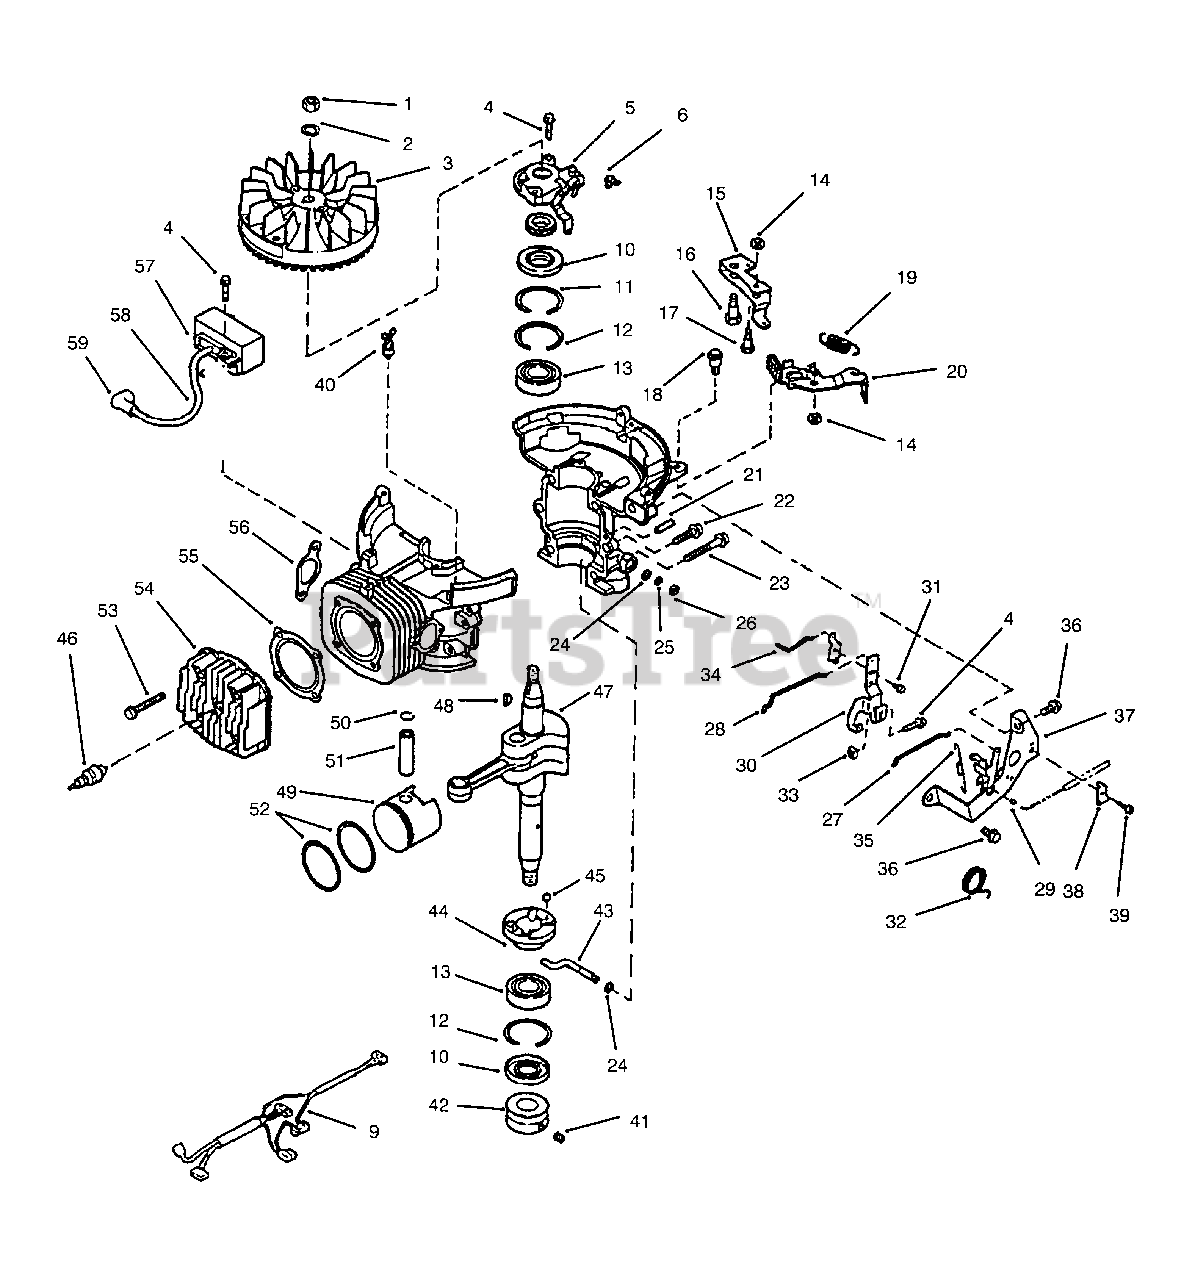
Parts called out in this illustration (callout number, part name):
1	Nut-Flywheel
2	Lockwasher
3	Flywheel (Model No.10590)
3	Flywheel (Model No.10591)
5	Oil Pump Kit w/Oil Lines (Incl. Ref. No. 6)
6	Clamp-Oil Line
9	Wire Harness (10591)
9	Wire Harness (10590)
10	Oil Seal-Crankshaft
11	Ring-Retaining
12	Ring-Retaining
13	Bearing-Crankshaft
14	Nut (Model No.10590)
15	Brake Actuator (Model No.10590)
16	Shoulder Bolt
17	Shoulder Bolt (Model No.10590)
18	Shoulder Bolt (Model No.10590)
19	Brake Spring (Model No.10590)
20	Brake & Switch (Model No.10590)
21	Pin-Taper
24	Washer-Governor Shaft
25	Ring-Retain.-Gov. Shaft
26	Seal-Oil, Governor Shaft
27	Rod-Choke
28	Rod-Throttle
29	Retainer-Throttle Wire
30	Kit-Gov. & Oil Pump Lever (Incl. Ref. No. 31)
32	Spring-Torsion
34	Rod-Oil Pump Control
35	Spring-Governor
37	Assy.-Governor Bracket (Model No.10590) (Incl. Ref. No. 32)
37	Assy.-Bracket & Switch (Model No.10591) (Incl. Ref. No. 32)
38	Clamp-Throttle Cable
40	Wire Tie (Model No.10591)
41	Screw-Set, Engine Pulley
42	Pulley-Engine
43	Shaft-Governor
44	Ramp-Governor
45	Ball-Governor
46	Spark Plug
47	Crankshaft & Conn. Rod (Model No. 10590)
47	Crankshaft & Conn. Rod (Model No.10591)
49	Assy.-Piston & Ring (Std.) (Incl. Ref. No. 50-52)
49	Assy.-Piston & Ring (0.020" Oversize) (Inc 50-52)
50	Ring-Retaining
51	Pin-Wrist
52	Ring Set (Standard)
52	Ring Set (0.020" Oversize)
53	Screw-Cyl. Head to Block
54	Head-Cylinder
55	Gasket-Head
56	Gasket-Exhaust
57	Module-C.D. Ignition (Incl. Ref. No. 58-59)
58	High Tension Lead & Cover (Incl. Ref. No. 59)
59	Assy.-Cover & Terminal
